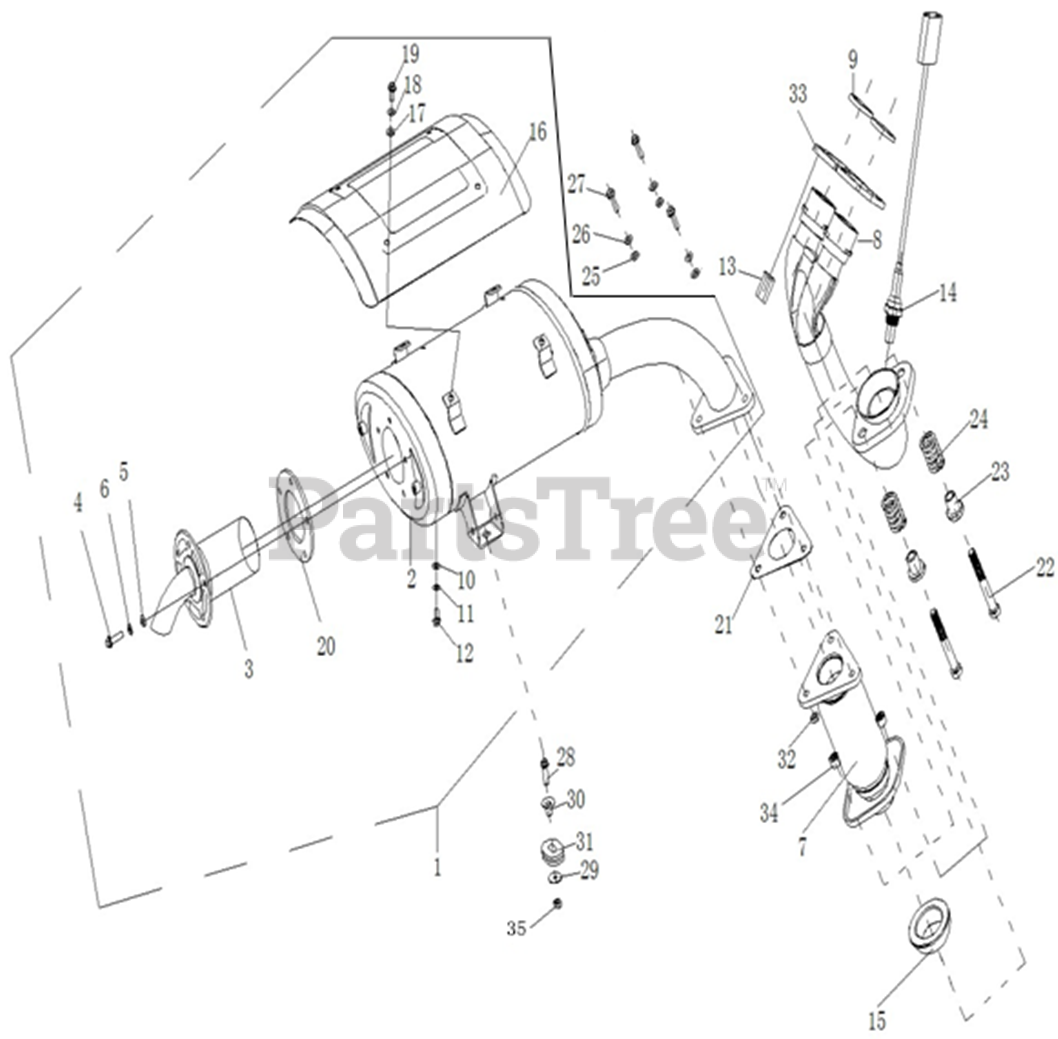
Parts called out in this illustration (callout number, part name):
1	MUFFLER ASSEMBLY
4	FLANGE HEAD BOLT M6-0.75x16
5	FLAT WASHER
6	SPRING WASHER
7	FLEX EXHAUST PIPE I
8	HEADER EXHAUST PIPE I
9	EXHAUST PIPE GASKET 33X42X6
11	SPRING WASHER
12	HEXAGON BOLT M10X1.25X16
13	CAP NUT M8x22
14	OXYGEN SENSOR ASSEMBLY-EFI
15	EXHAUST GASKET
16	MUFFLER HEAT SHIELD
17	WASHER - SPRING LOCK 8
18	FLAT WASHER 6x18x1
19	BOLT HEX SOCKET M6X16
20	TAILPIPE GASKET
21	EXHAUST PIPE GASKET
22	HEX HEAD FLANGE BOLT M10X1.25X80
23	EXHAUST SPACER
24	EXHAUST VALVE SPRING
26	SPRING WASHER-8
27	HEXAGON FLANGE BOLT M8X30
28	HEX FLANGE BOLT M6X25
29	FLAT WASHER 6X25X2
31	RUBBER WASHER
32	HEXAGON FLANGE NUT M8
33	EXHAUST FLANGE
34	NUT M10X1.25
35	HEXAGON FLANGE LOCKED NUT M6
